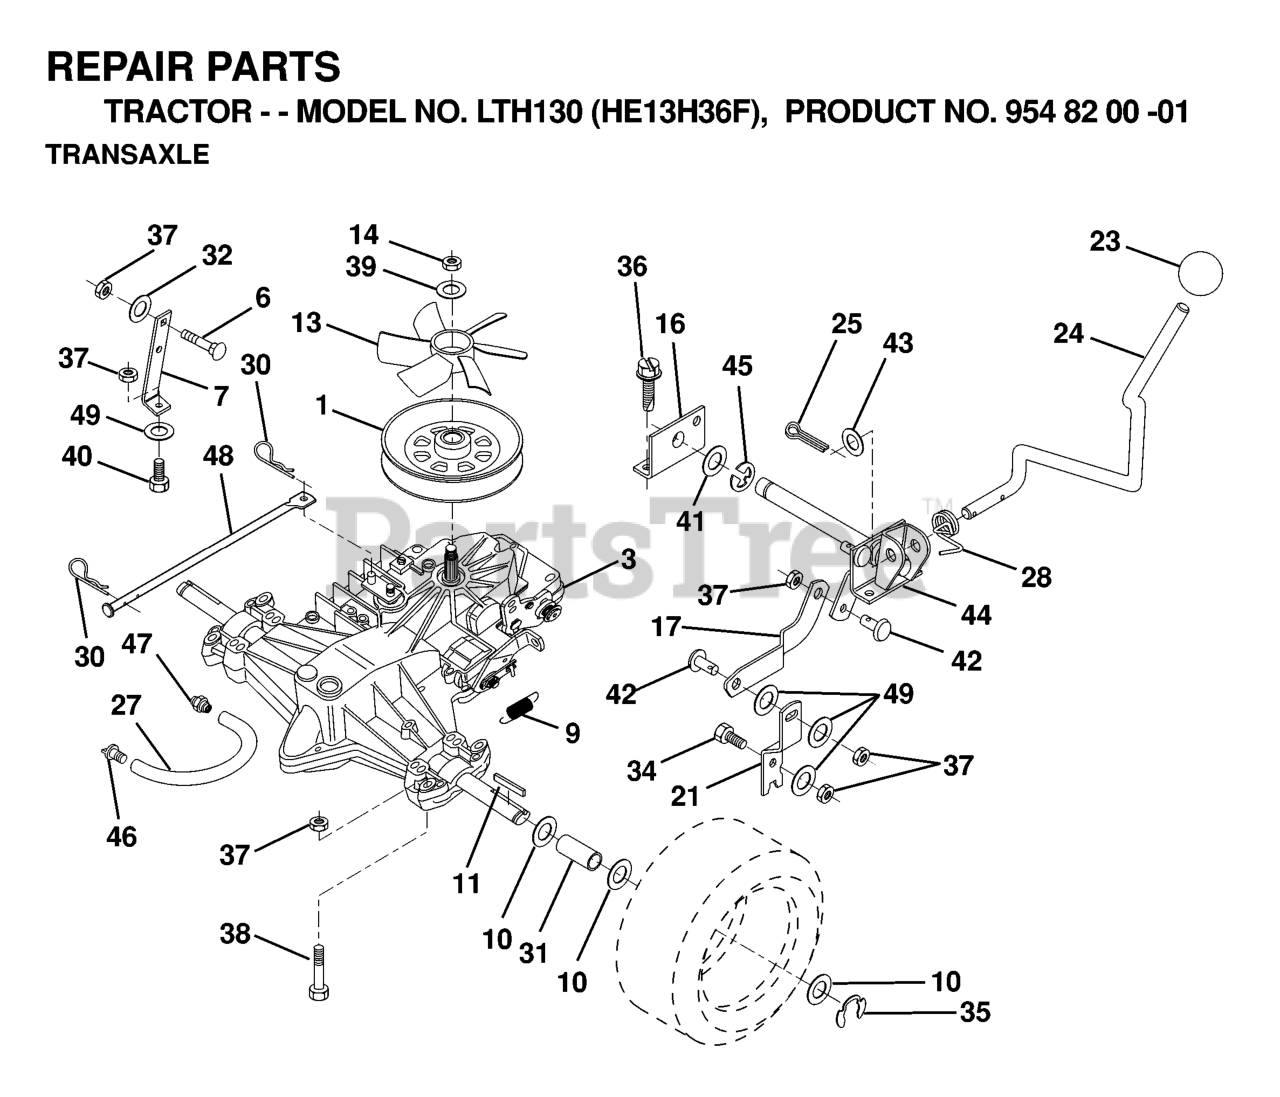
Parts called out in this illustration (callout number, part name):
1	PULLEY.V-GROOVE
6	RP BOLT 5/16-18 X3/4 ZN/YEL GR
9	SPRING,BRAKE RETURN
11	SQUARE KEY
13	FAN.TRANSMISSION.HYDRO.6"
16	SUPPORT, SHIFT HANDLE
17	LINK, SHIFT
21	LEVER, SHIFT
23	KNOB.DUCKHEAD.1/2
24	ROD, SHIFTER
25	PIN COTTER
27	LINE FUEL HYD 4"
28	SPRING, TORSION
30	RETAINER M
31	SPACER SPLIT
32	WASHER
34	BOLT RB
36	SCREW
37	NUT.71038.31-18.HEX.NYLOCK
40	BOLT
41	Washer 21/32 x 1-1/4 x 13 Ga.
43	WASHER
44	PIVOT SHAFT
45	RETAINING RING LT
46	CAP, VENT ASSY
47	O-RING KIT 70110
49	WASHER M
